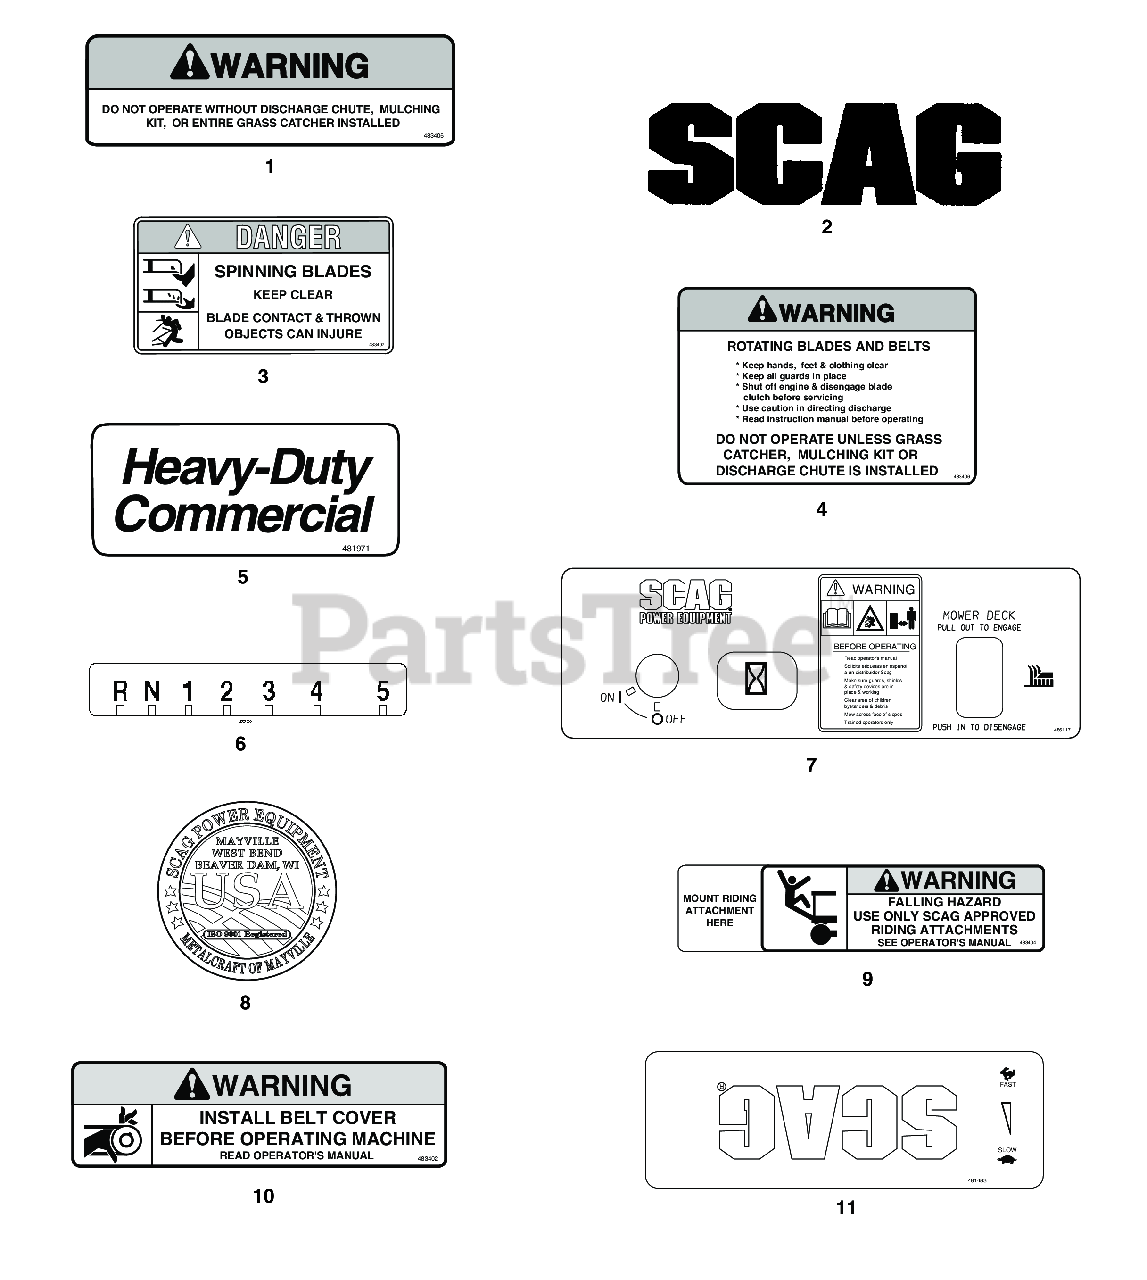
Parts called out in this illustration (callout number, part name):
1	Decal, Warning-Discharge
2	Decal, Scag Logo ( Cutter Deck)
3	Decal, Danger-Spinning Blades
4	Decal, Warning - Rotating Blades
5	Decal, Heavy Duty Commercial
6	Decal, Shift Index
7	Decal, Instrument Panel - Rear
8	Decal, Metalcraft - USA
9	Decal, Sulky Attachment
10	Decal, Warning - Belt Cover
11	Decal, Instrument Panel - Front
